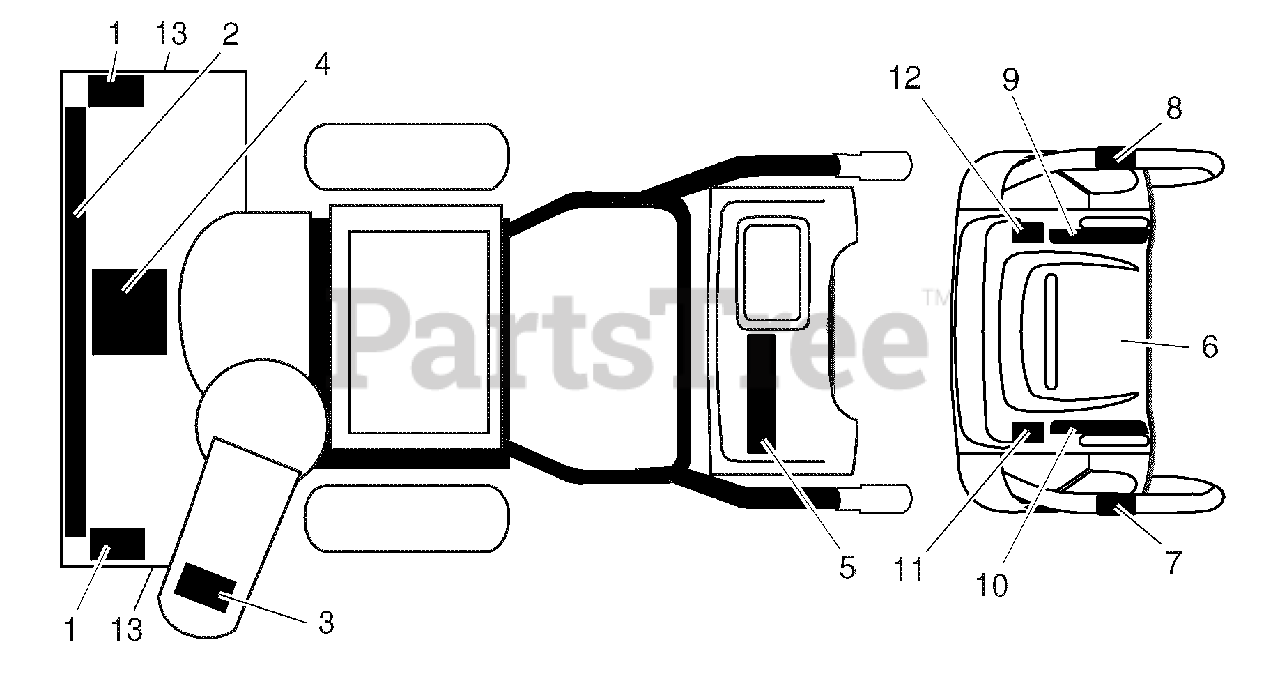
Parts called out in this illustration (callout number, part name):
1	Decal, Danger
2	Decal, Husqvarna
3	Decal, Danger, Deflector
4	Decal, Danger
5	Decal, Husqvarna, 1130SBEXP
6	Decal, Instruction
7	Decal, Traction Lever
8	Decal, Auger Lever
9	Decal, Auger Safety
10	Decal, Speed Control
11	Decal, LH Trigger
12	Decal, RH Trigger
13	Decal, Husqvarna, Crown
13	Owner’s Manual, English
13	Owner’s Manual, French
